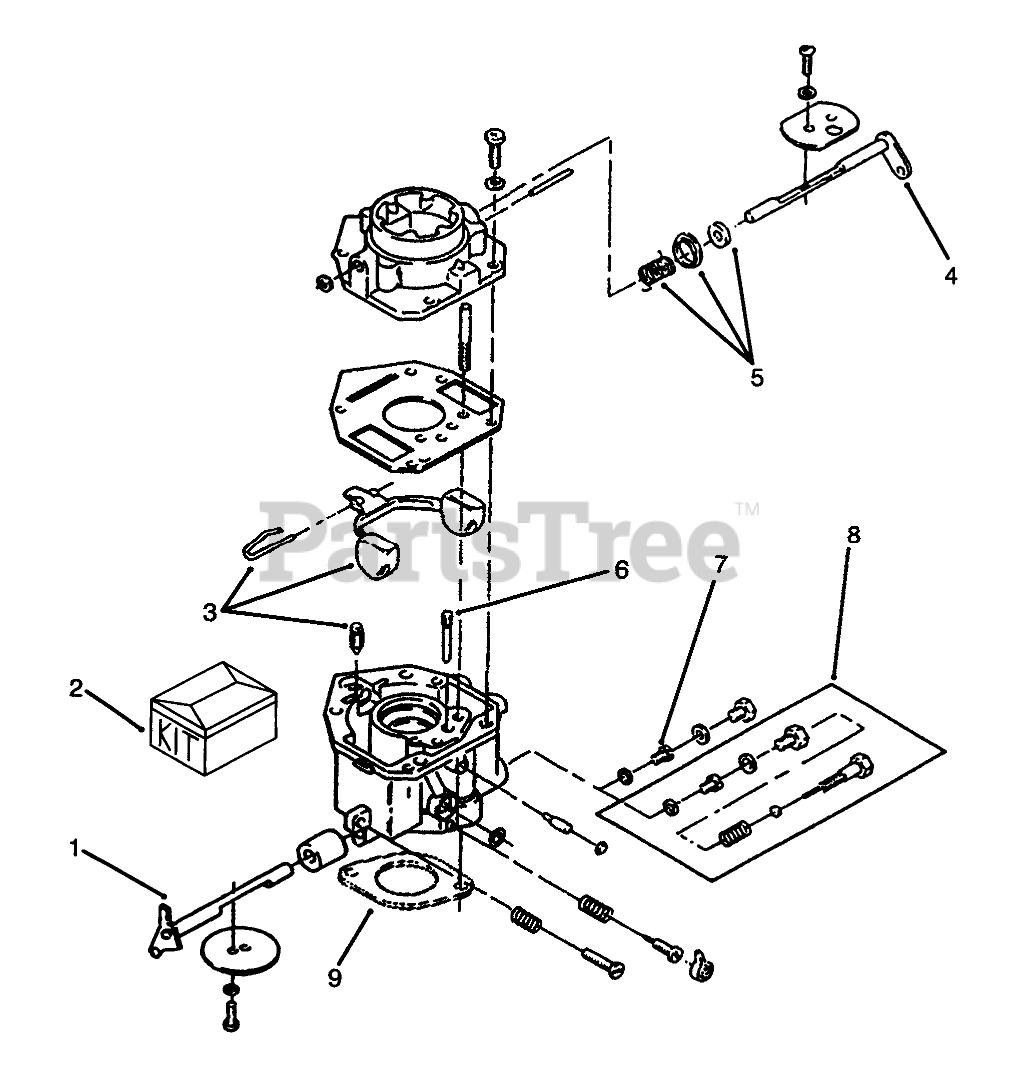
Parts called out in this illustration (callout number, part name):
1	Kit-Shaft, Throttle (Includes Valve Setscrew, Air Filter, & Throttle Valve)
2	Kit-Repair (Includes Screw & Plug Package, Gasket Package, Float Valve, Idle Adj. Needle & Spring, Mounting Gaskets, & Idle Limit Cap)
3	Kit-Float (Includes Float, Pin & Valve) Before Serial No. 5900178
4	Kit-Shaft, Choke (Incl. Choke Valve, Valve Setscrew, & Air Filter)
5	Kit-Lever, Choke (Incl. Choke Lever Ring, Choke Spring, & Choke Collar)
6	IDLE-JET
7	POWER JET
8	FIXED-JET
9	GASKET-CARBURETOR
